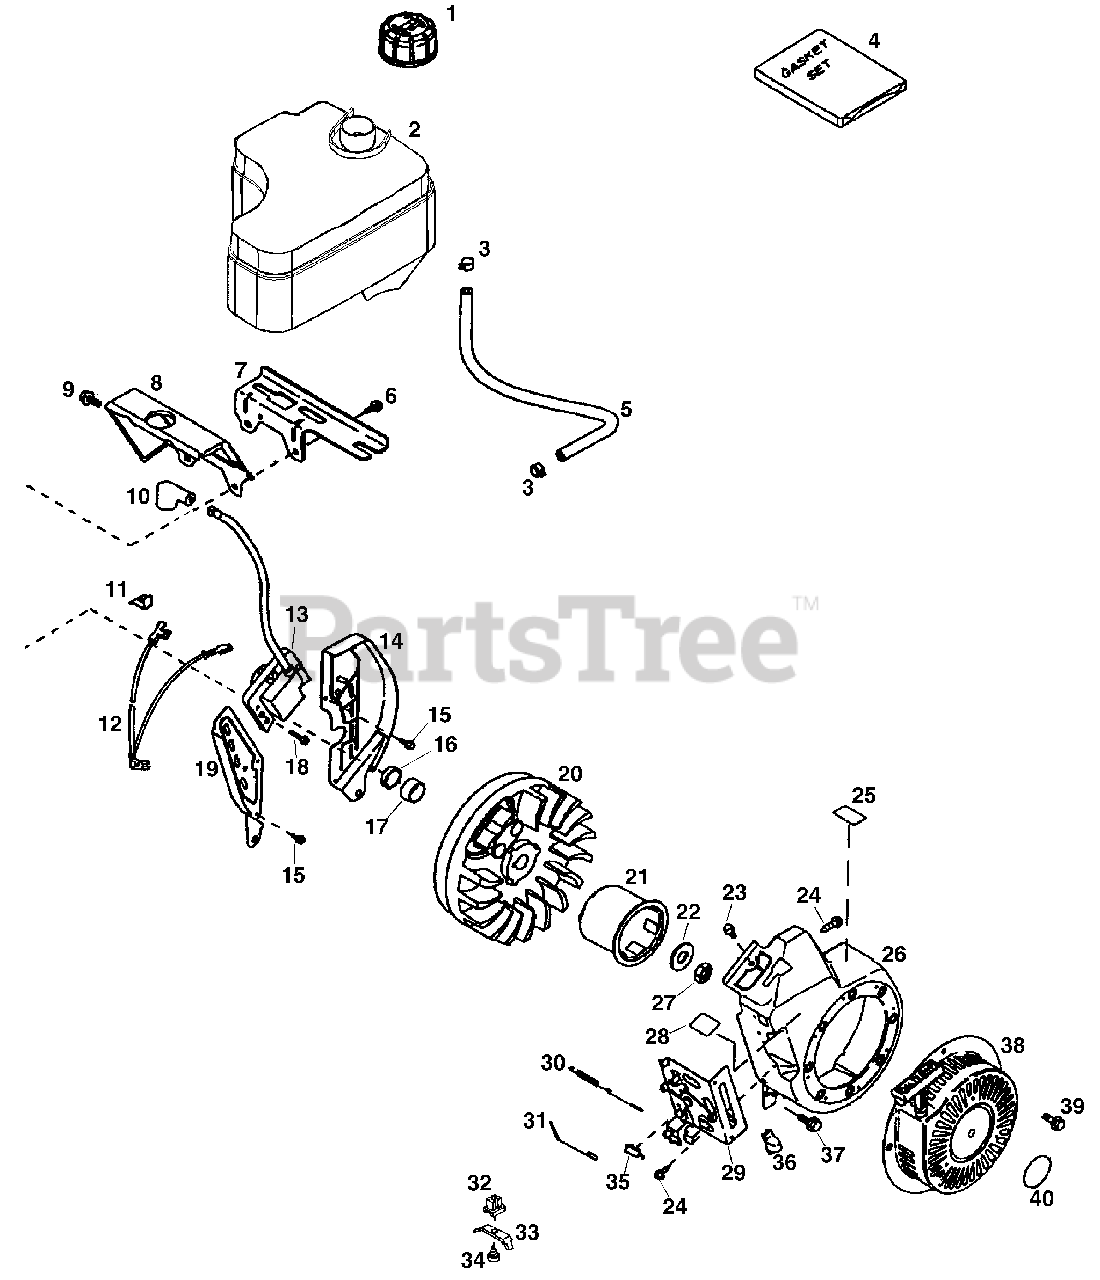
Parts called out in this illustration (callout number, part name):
1	Fuel Cap
2	Fuel Tank
3	Fuel Line Clamp
4	Gasket Set
5	Fuel Line
6	Screw, 1/4-20 x 7/8"
7	Fuel Tank Bracket
8	Blower Housing Extension
9	Screw, 10-24 x 9/16".
10	Spark Plug Cover
11	Wire Clip
12	Ground Wire
13	Solid State Ignition
14	Air Baffle (Right)
15	Screw, 10-24 x 9/16".
18	Screw, Torx T-15, 15/16".
19	Air Baffle (Left)
21	Starter Cup
22	Bell Washer
23	Screw, 1/4-20 x 31/64".
24	Screw, 10-32 x 1/2".
25	Lube Decal
26	Blower Housing
27	Flywheel Nut
28	Speed Control Decal
29	Control Bracket
30	Extension Spring
31	Governor Link
33	Ground Terminal
34	Screw, 8-32 x 3/8".
36	Control Knob
37	Screw, 1/4-20 x 31/64".
38	Rewind Starter
39	Screw, 1/4-20 x 31/64".
40	Starter Decal
